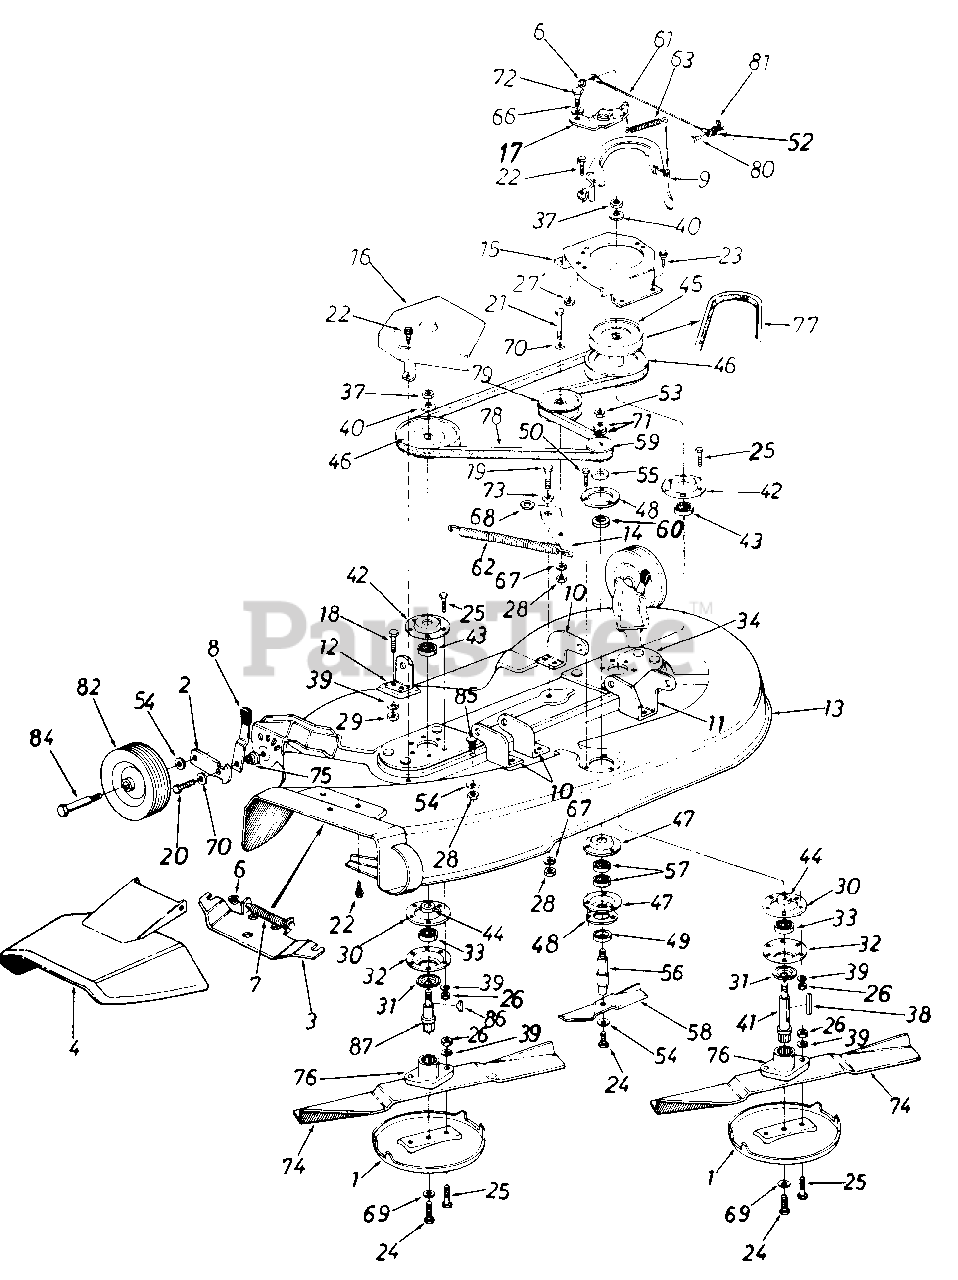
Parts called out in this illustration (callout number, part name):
1	Anti-Scalp Plate
2	Bar-Wheel Pivot
3	Adapter Plate
4	Chute Cover Ass'y.
6	Cap Speed Nut 1/4" Rod
7	Torsion Spring
8	Spring Lever Ass'y.
9	Belt Guard
12	Deck Hanger Bracket
13	44" Deck Ass'y.
14	Idler Bracket
15	Pulley Cover-L.H.
18	Hex Bolt 5/16-18 x .75" Lg.*
20	Hex Bolt 3/8-24 x 1.25" Lg.*
21	Hex Bolt 3/8-24 x 1.50" Lg.*
22	Hex Wash. S-Tapp Scr. '/4-20 x .50
23	Hex Wash. Hd. Tapp Scr. 5/16-18 x .75" Lg.
24	Hex Cent. L-Bolt 3/8-24 x .88" Lg.
25	Hex Bolt Special 5/16-24 x 1.0" Lg.
26	Hex Nut 5/16-24 Thd.*
27	Hex Cent. L-Nut 5/16-18 Thd.
28	Hex Nut 3/8-24 Thd.*
29	Hex Nut 5/16-18 Thd.*
30	Reinforcement Plate
31	Bearing Shield
32	Open Brg. Housing 1.85 I.D.
33	Ball Brg. .787" I.D. x 1.85" O.D. x .551
34	Spindle Mounting Plate \ Ass'y.
37	Hex Jam Nut 5/8-18 Thd.*
38	Sq. Key 3/16" x 2.25" Lg.
39	L-Wash. 5/16" I.D.*
40	Bell-Wash. .630" I.D. x 1.25" O.D.
41	44" Deck Blade Spindle
42	Bearing Housing 1.85" I.D.
43	Ball Brg. .787" I.D. x 1.85" O.D. x .551
44	Spacer 1.0" O.D. x .790" I.D.
45	5/8 "V"-Pulley .79" I.D. x 5.75" O.D.
46	"V"-Pulley .79" I.D. x 6.50" O.D.
47	Bearing Housing 1-3/8" I.D.
48	Reinforcement Plate
49	Bearing Shield
50	Hex Wash. Hd. B-Tap Scr. 1/4 x.75" Lg.
52	Fl-Wash. .20" I.D. x .62" O.D.
53	Hex Jam Nut 1/2-20 Thd.
54	Bell-Wash. .400" I.D. x .88" O.D.
55	Fl-Wash. .635" I.D. x 1.04" O.D.
56	6.5" Blade Spindle
57	Ball Brg. .62" I.D. x 1.38" O.D. x .44
58	6.5" Blade
59	1/2" "V"-Pulley Half .625" I.D. x 2.25" O.D.
60	Fl-Wash. 518" I.D. x 15/16" O.D.
61	Brake Cable 11.75" Lg.
62	Extension Spring .73" O.D. x 4.31 " Lg.
63	Ext. Spring .50" x 2.51" Lg.
66	Spring Wash. .445" I.D. x .75" O.D.
67	L-Wash. 3/8" I.D.
68	Spring Wash. .625" I.D. x .885" O.D.
69	L-Wash. 3/8" I.D.
70	Bell-Wash. .400" I.D. x 1.13" O.D.
71	Bell-Wash. .505" I.D. x 1.001' O.D.
72	Shld. Bolt .437" Dia. x .180
73	Shld. Spacer .625" I.D.
74	21" Blade
75	Shld. Spacer
76	Blade Adapter
77	"V"-Belt 1/2" x 52.0" Lg.
78	"V"-Belt 1/2" x 74.0" Lg.
79	Fl-Idler w/Flanges 3.50" O.D.
80	Clevis Pin 1/4" Dia. x .53" Lg
81	Intern. Cotter Pin 5/16" Dia.
82	Deck Wheel 6.0" x 1.38
84	Shld. Bolt 3/8-16 x 1.41
85	Rib Neck Bolt
86	Sq. Key 3/16" x 3/16" x .75" Lg.
87	44" Deck Blade Spindle
